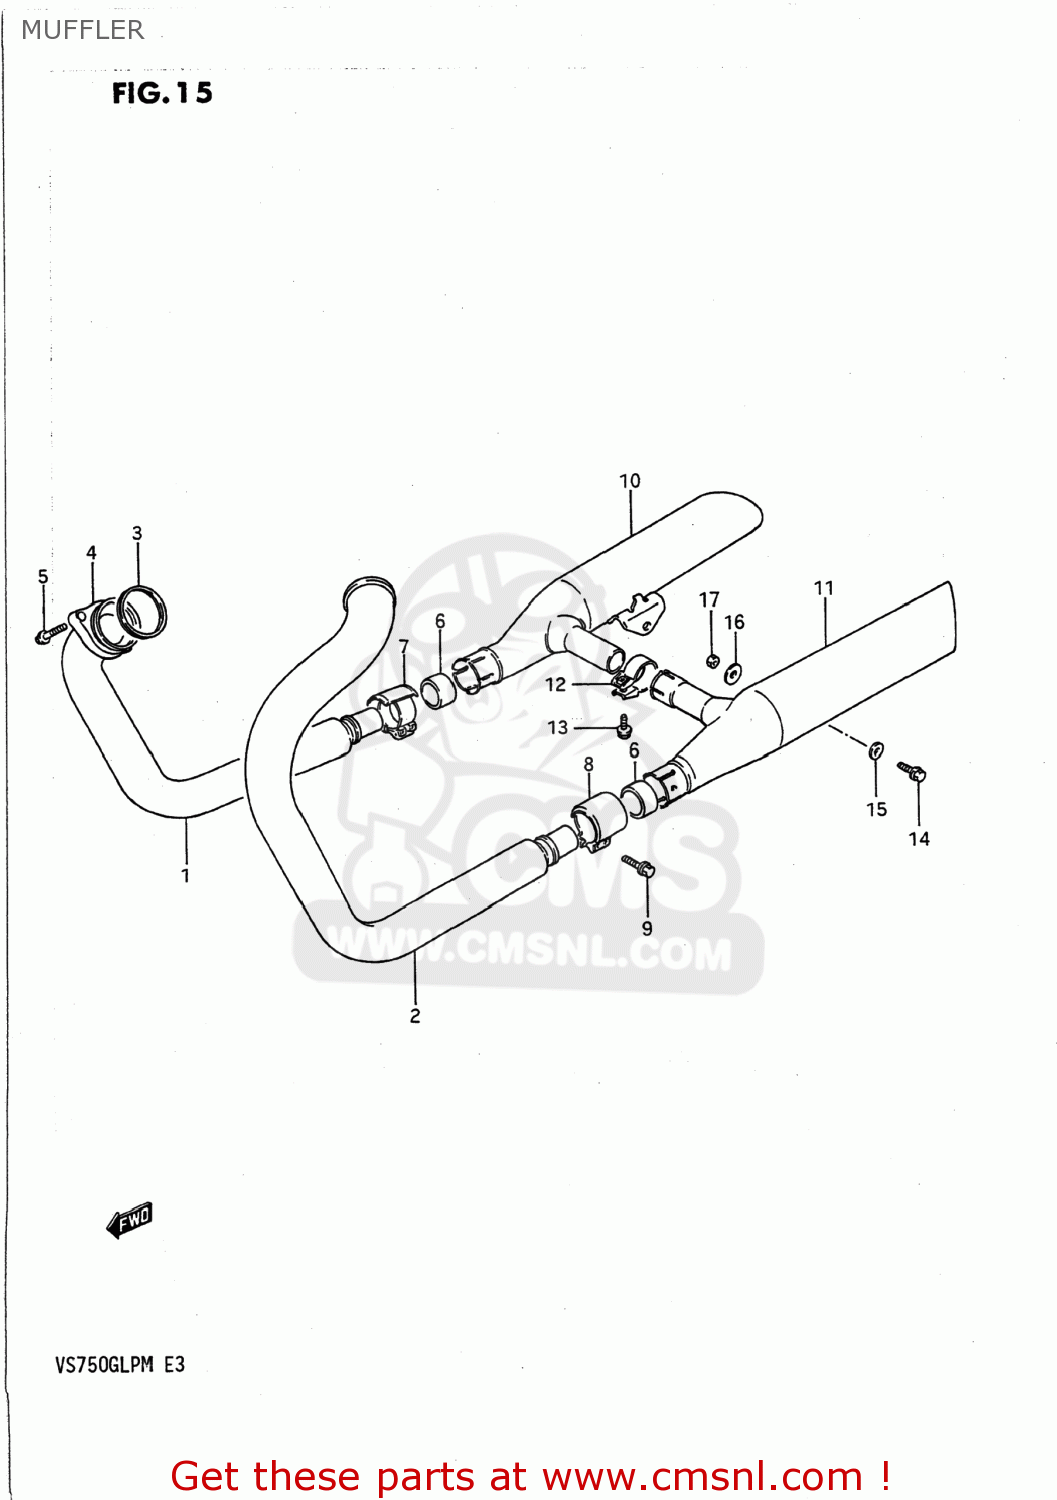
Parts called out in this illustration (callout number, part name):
1	PIPE,EXHAUST
2	PIPE,EXHAUST
3	GASKET,EXHAUST PIPE (NAS)
4	CLAMP,EXHAUST PIPE
5	BOLT(8X35)
6	CONNECTOR,MUFFLER
7	CLAMP,MUFFLER CONNECTOR,R
8	CLAMP,MUFFLER CONNECTOR,L
9	BOLT
10	BODY,MUFFLER
11	BODY,MUFFLER
12	CLAMP,EXHAUST COUPLER
13	BOLT 6X25
14	BOLT
15	WASHER
16	WASHER
17	NUT
